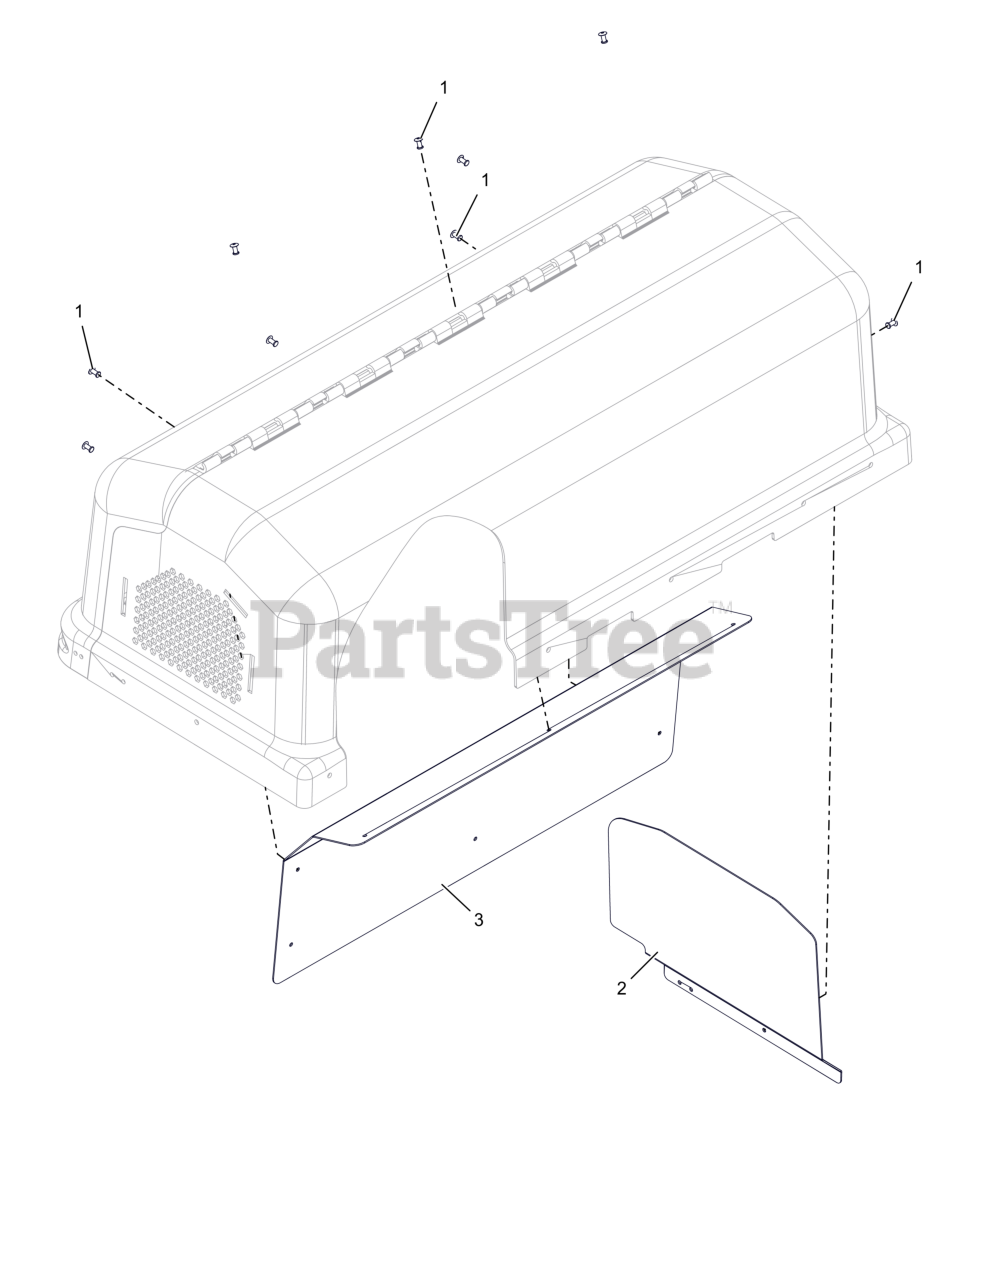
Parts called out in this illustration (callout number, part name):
1	RIVET, #66 STEEL POP PD BLACK
2	GUARD- HOUSING SIDE (BLK)
3	GUARD- HOUSING DOOR
